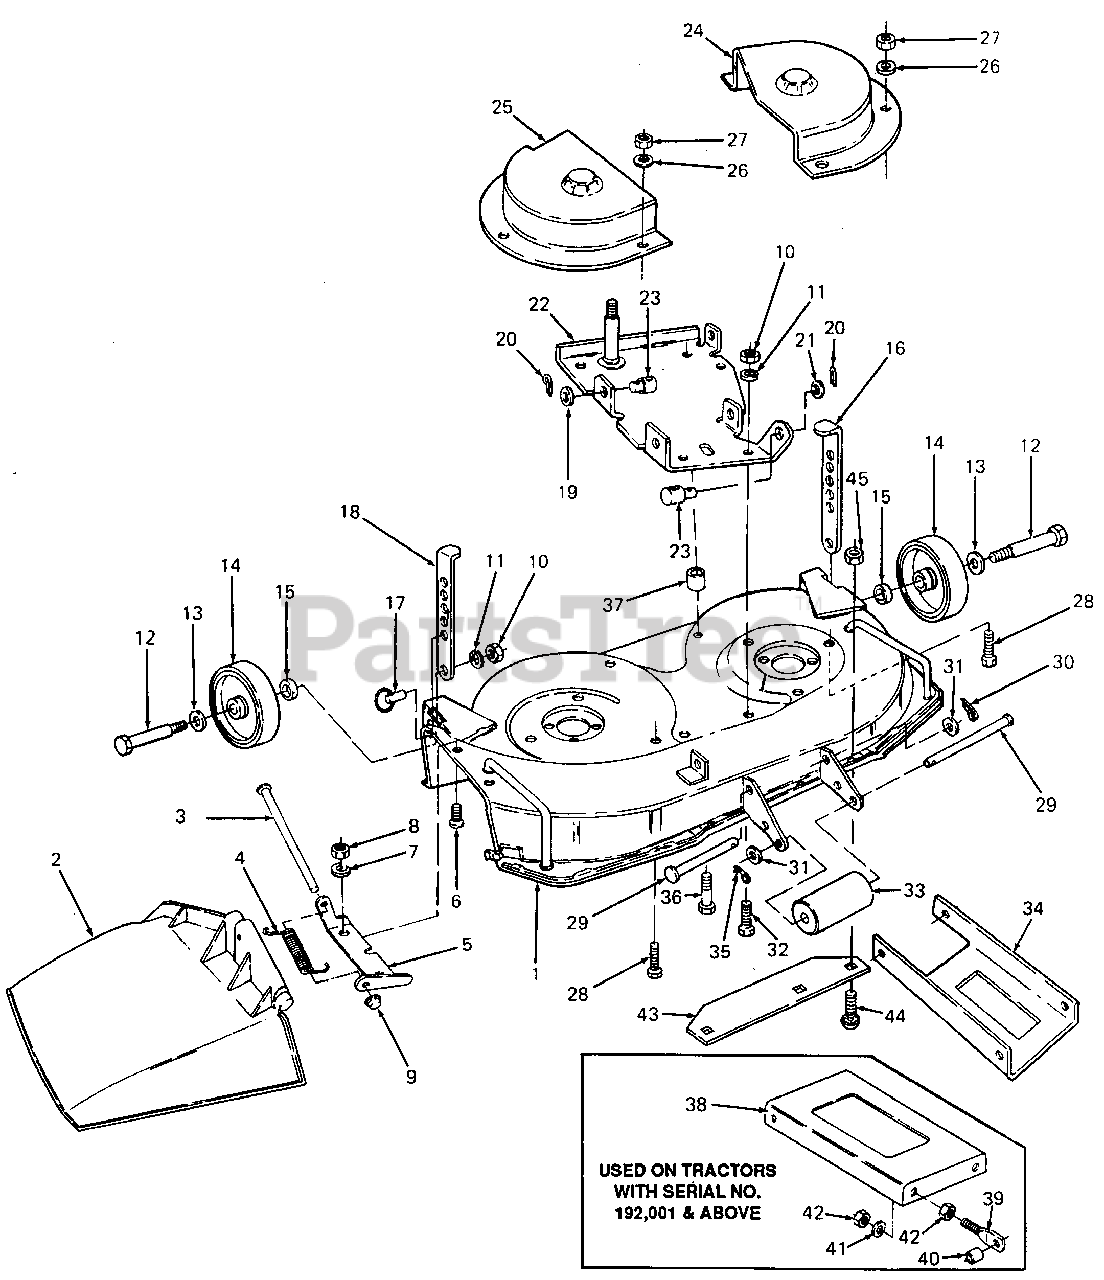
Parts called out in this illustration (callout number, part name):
2	Chute Kit w/Graphic
3	Pin, Hinge, 0.25 Dia X 6.75 Lg
4	Spring, Torsion
5	Bracket, Hinge Mtg
6	Screw, Truss Machine, 1/4-20 X .75 Lg, Phillips
7	Washer, Lock, 1/4 Dia
8	Nut, Hex, 1/4-20 GR5
9	Nut, Cap Speed
10	Nut, Hex, 3/8-16 GR5
11	Washer, Lock, 3/8 Dia
12	Bolt, Shld, 0.50 Dia X 1.62 Lg X 3/8-16
13	Washer, Flat, 0.510 ID X 1.12 OD X 0.1000 Thk
14	Wheel, Gauge, 5" Dia
15	Spacer, 0.385 X .075 X 0.75 Lg
16	Bar, Height Adjustment LH
17	Pin, Clevis w/Detent Ball
18	Bar, Height Adjustment RH
19	Washer, Flat, .406 X 1.0 X .03
20	Pin, Cotter, 1/8 Dia X 1.0 Lg
21	Washer, Flat, .406 X .75 X .06
24	Cover, Belt LH
25	Cover, Belt RH
26	Washer, Flat, 0.34 X 0.68 X 0.06
27	Nut, Hex, 5/16-18 GR5
28	Screw, Hex Head Cutting, 5/16-18 X 0.62 Lg
29	Pin, Clevis, 1/2 X 7.68
30	Pin, Internal Cotter
31	Washer, Flat, 0.510 X 1.0 X 0.06
32	Bolt, Short Neck Carr, 3/8-16 X 0.75 Lg GR5
33	Roller, Front
34	Bracket, Deck Front Support
35	Pin, Cotter, 3/16 Dia X 1.0 Lg
36	Bolt, Carriage, 3/8-16 X 1.25
37	Spacer, 0.390/0.400 ID X 0.75 OD X 0.44 Lg
38	Bracket, Deck Front Support
39	Eye Bolt
40	Sleeve
41	Washer, Lock, 1/2
42	Nut, Hex, 1/2-13 GR5
45	Nut, Sems, 1/4-20
